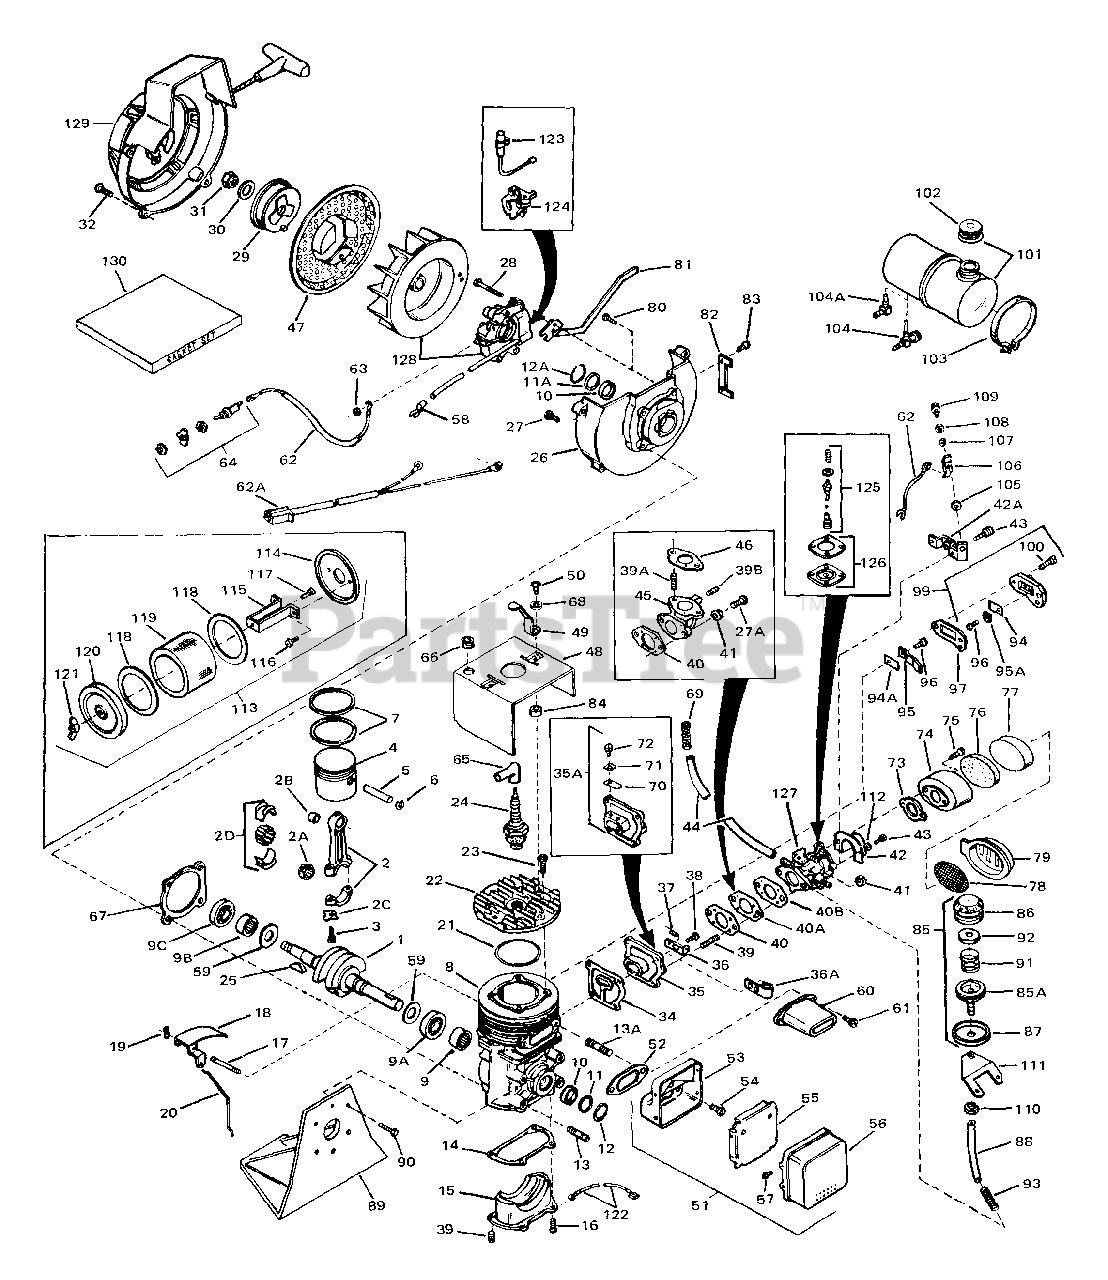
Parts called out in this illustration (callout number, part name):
1	"Crankshaft
2	Rod Assy., Connecting
2B	Bearing, Cartridge
3	Screw, Connecting rod
4	Piston
5	Pin, Piston
6	Ring, Piston pin retaining
7	Ring Set, Piston
8	Block Assy., Cylinder
9A	Bearing, Ball
9B	Bearing, Cartridge
10	Seal, Crankshaft
11	Retainer, Crankshaft seal
11A	Retainer, Crankshaft seal
12	Spring, Crankshaft seal retainer
12A	Spring, Crankshaft seal retainer
14	Gasket, Cover
15	Plate, Cover
17	Shaft, Air vane
18	Vane Assy., Air
19	Clip, Air vane
20	Link, Governor
21	Gasket, Cylinder head
22	Head, Cylinder
24	Plug, Spark
24	Resistor Spark Plug (Canadian Regulat ions
25	Key, Woodruff
26	Base Assy., Shroud
27	Screw
29	Cup, Starter
30	Washer, Flat
31	Nut, Flywheel
34	Gasket, Adapter cover
35	Cover, Adapter
36	Lever, Adjusting
37	Spring, Adjusting lever
38	Screw, Pan flex hd., 10-24 x 5/8
40	Gasket, Carburetor
40B	Gasket, Carburetor
41	Nut, Hex, 1/4-20
41	Nut, Hex, 1/4-28
47	Screen, Air
48	Shroud, Cylinder
49	Lever,Stop
50	Screw
51	Muffler Assy.
52	Gasket, Exhaust
53	Base, Muffler
54	Screw
55	Baffle, Muffler
56	Cover, Muffler
58	Terminal, Lead wire
59	Washer, Thrust
67	Gasket, Shroud base
73	Gasket, Air filter
74	Body, Air filter
76	Screen, Air filter
77	Element, Air filter
78	Element, Air filter
79	Cover, Air filter
123	Condenser
124	Contact Assy., Breaker
125	Inlet Needle, Seat, Spring & Gasket A ssy.
126	Diaphragm Assy.
127	Carburetor
128	Magneto
129	Rewind Starter & Shroud Assy.
130	Gasket Set
